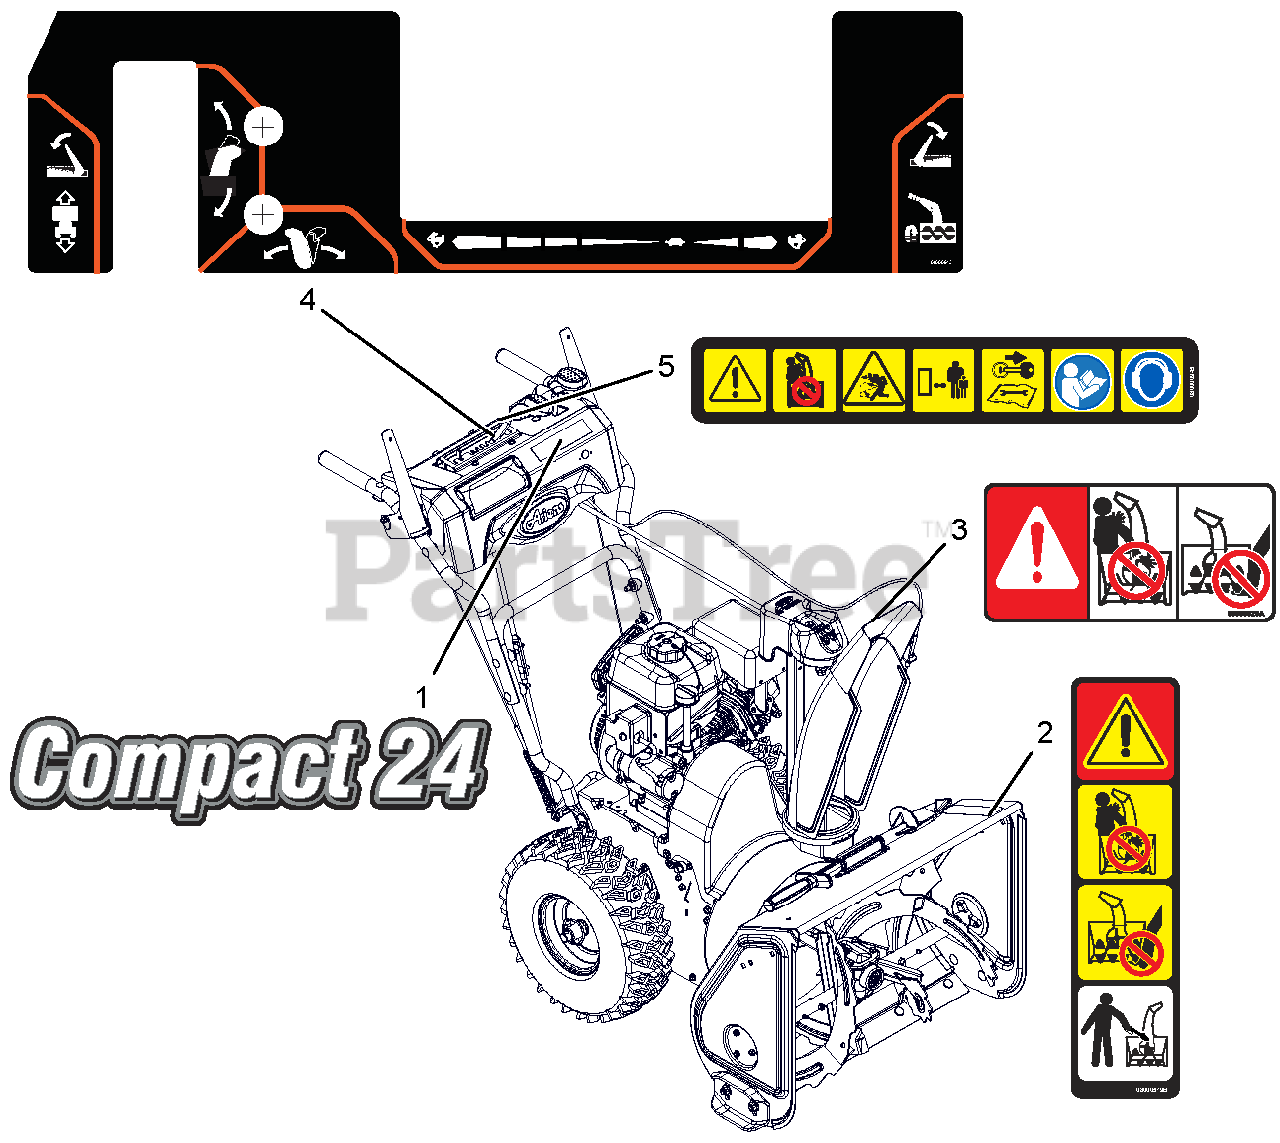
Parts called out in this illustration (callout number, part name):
1	DECAL, COMPACT 24
2	DECAL, DANGER - ROTATING PARTS
3	DECAL, DANGER
4	DECAL,CONTROL-COMP REMOTE
5	DECAL,DASH - SAFETY
